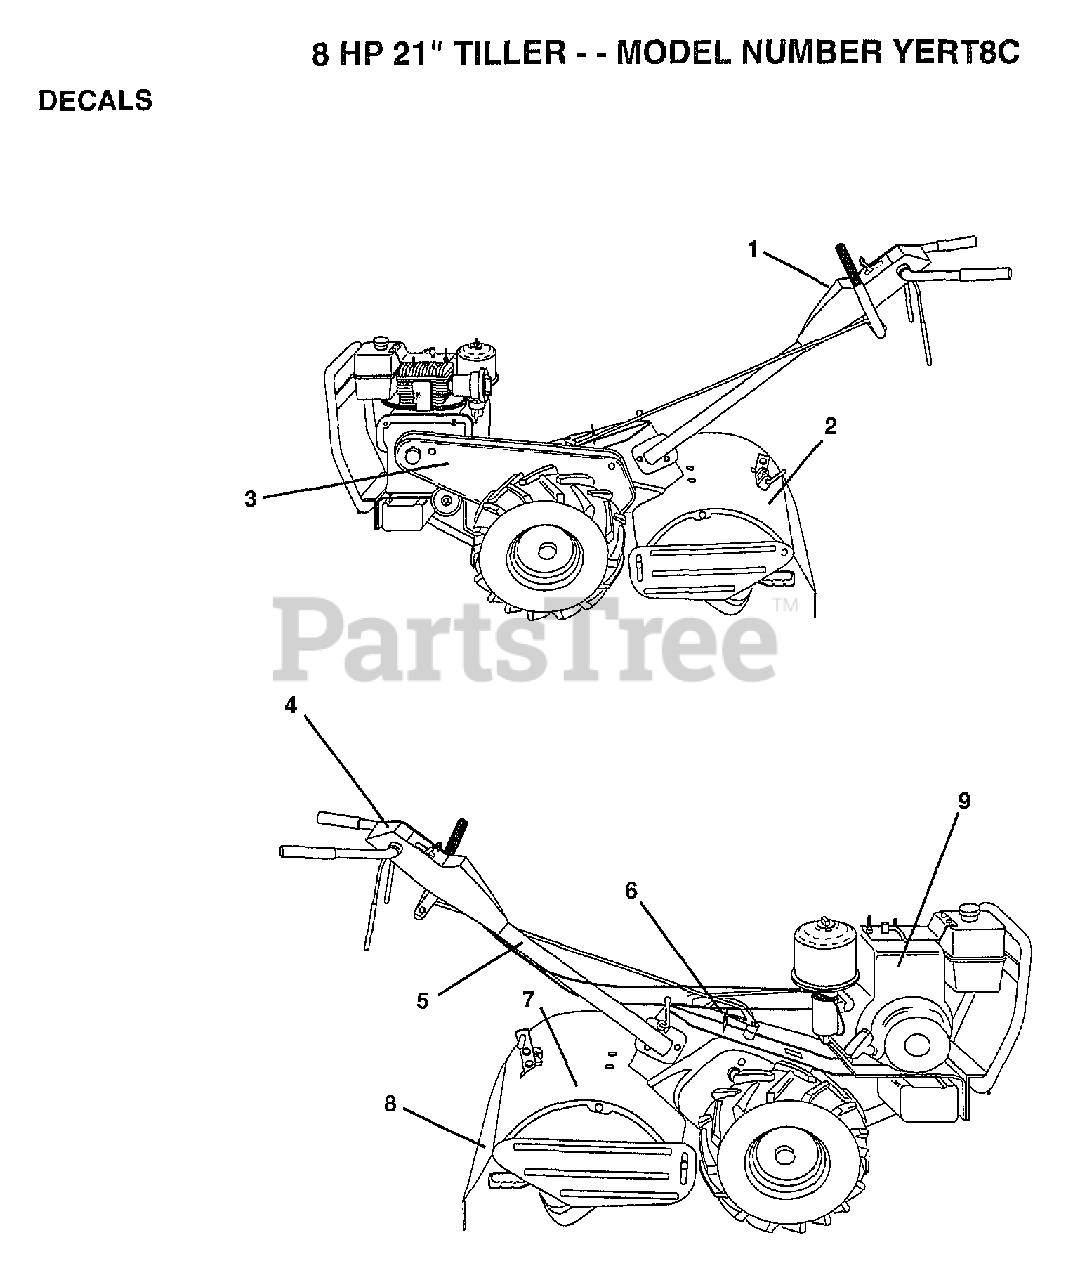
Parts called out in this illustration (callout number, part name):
1	DECAL.PNL.CONTROL
2	DECAL SHIELD TINE
3	DECAL LOGO GUARD
4	DECAL INST PNL 21
5	DECAL TI
6	DECAL INDICT SHIF
7	DECAL TI
9	DECAL, BRIGGS & STRATTON
